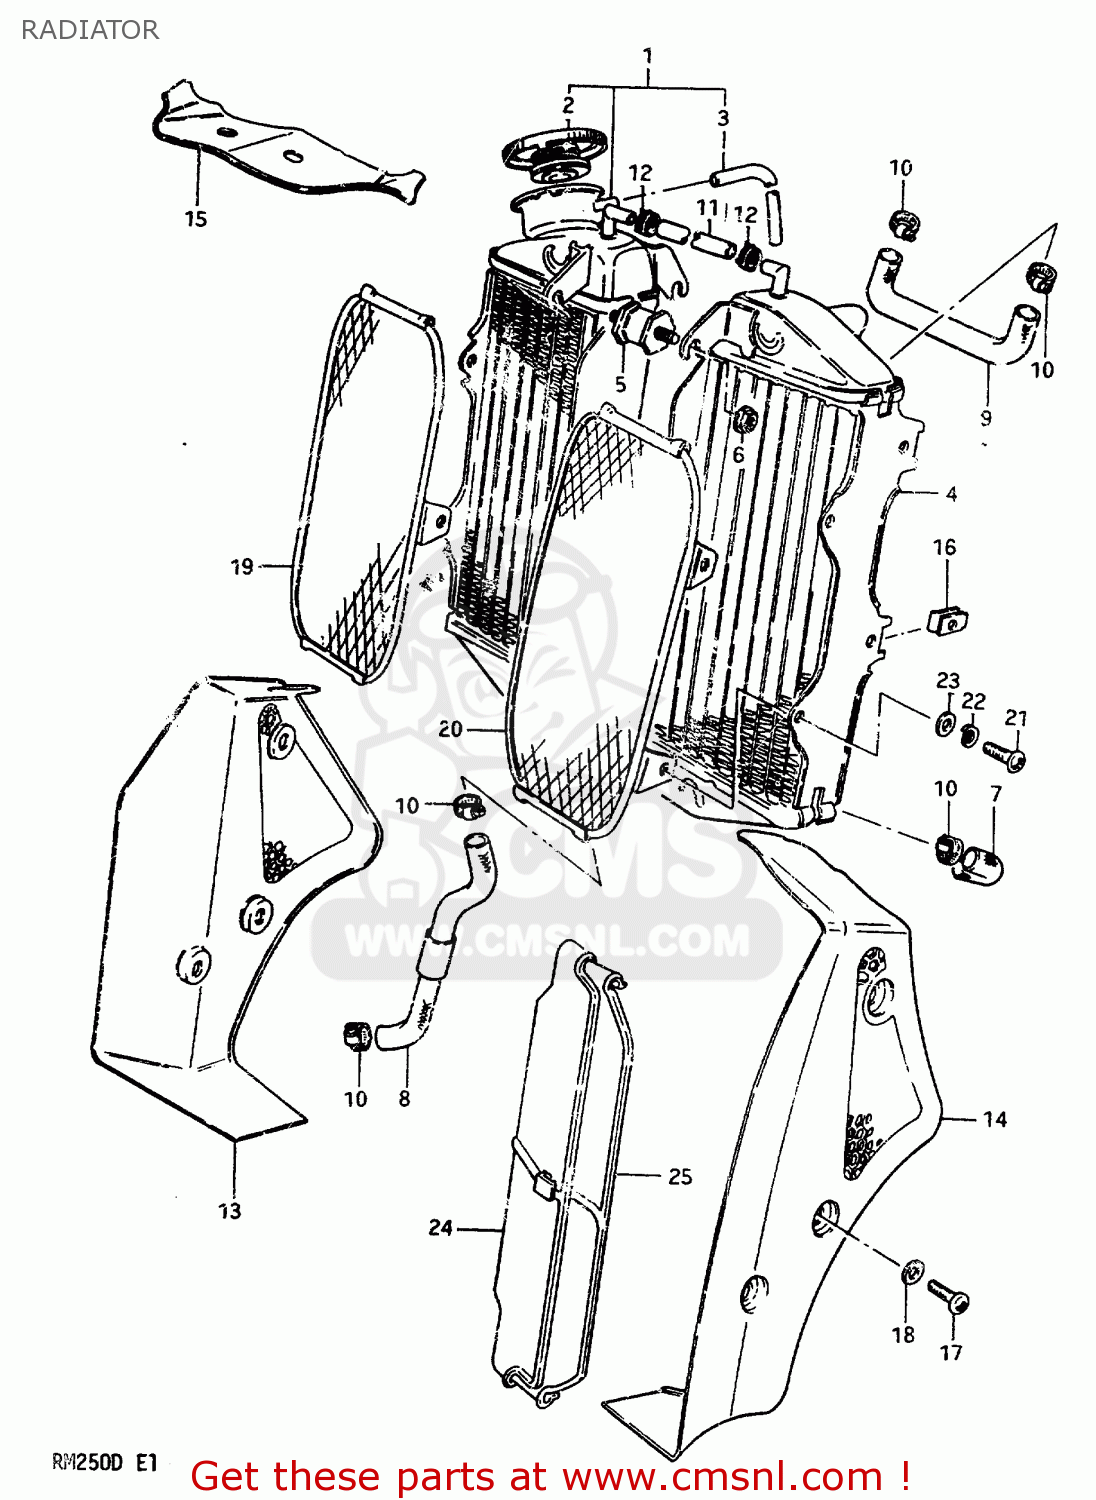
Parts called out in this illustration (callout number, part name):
1	RADIATOR ASSEMBLY,RIGHT
2	CAP,RADIATOR
3	HOSE,BREATHER
4	RADIATOR ASSEMBLY,LEFT
5	CUSHION,RADIATOR
6	NUT
7	HOSE,RADIATOR
8	HOSE,RADIATOR OUTLET
9	HOSE,RADIATOR JOINT
10	CLAMP
11	HOSE,WATER
12	CLIP
13	COVER,RADIATOR,R
14	COVER,RADIATOR,L
15	COVER,RADIATOR,UPPER
16	PLATE,RADIATOR COVER F
17	SCREW (5X12)
18	WASHER,5MM
19	BUMPER,RADIATOR,RIGHT
20	BUMPER,RADIATOR,LEFT
21	SCREW
22	LOCK WASHER
23	WASHER
24	LOUVER,RADIATOR MUD GUARD
25	LOUVER,RADIATOR MUD GUARD
